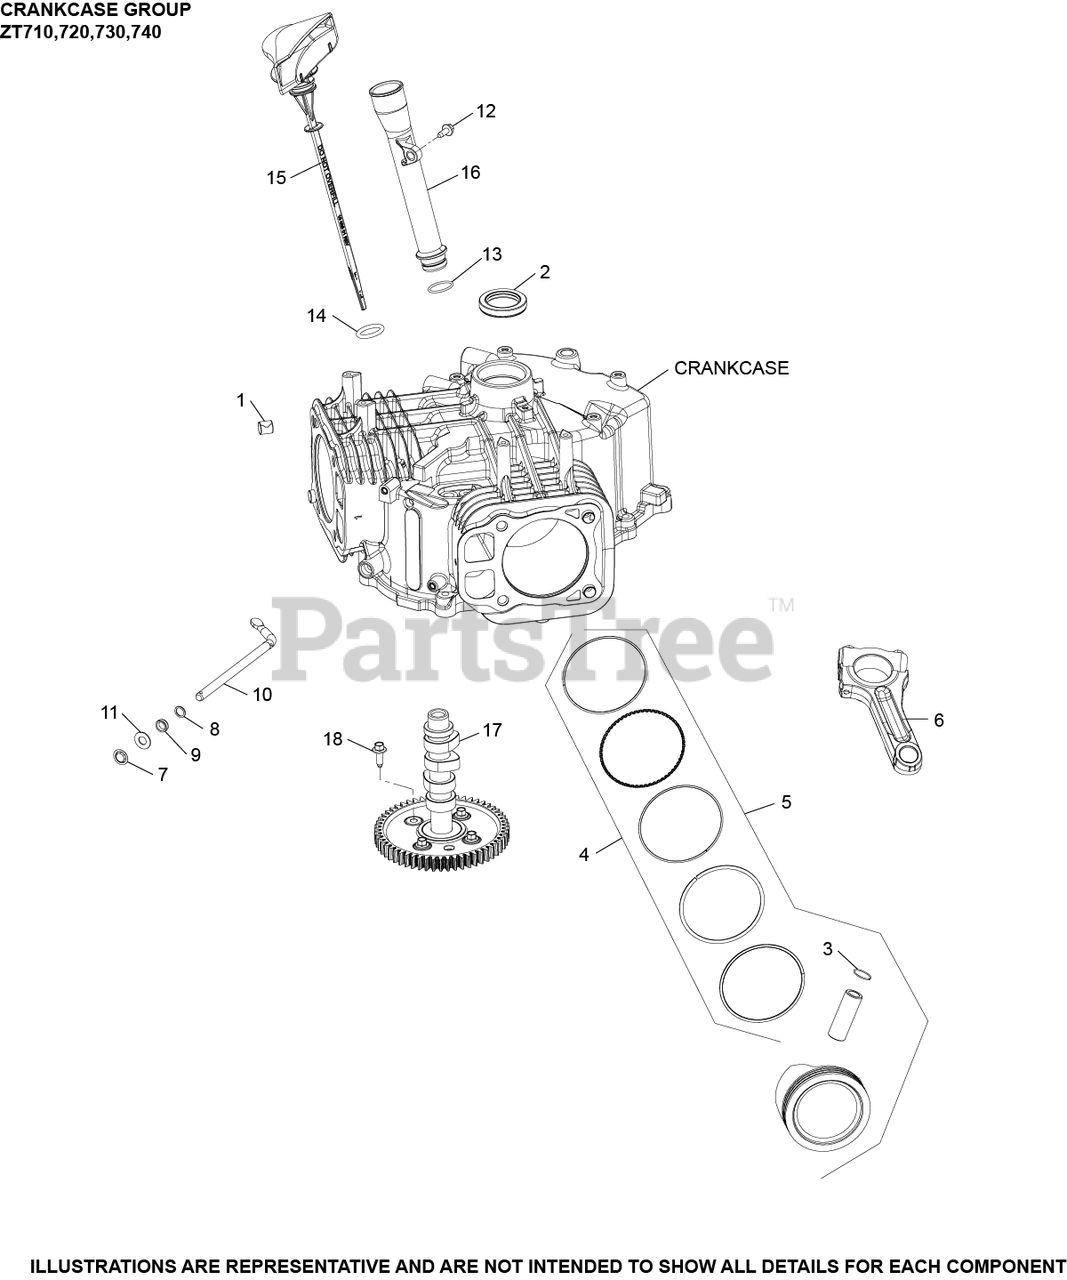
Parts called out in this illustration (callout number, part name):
1	PIN, LOCATING
2	SEAL, OIL (HELIX LIP)
3	RETAINER, PISTON PIN
4	RING SET(STD)STYLE B-1.2mm Tp RING THICK
4	RING SET(.08)STYLE B-1.2mm Tp RING THICK
4	RING SET(.25)STYLE B-1.2mm Tp RING THICK
4	RING SET(.50)STYLE B-1.2mm Tp RING THICK
5	PISTON W/RINGS (STYLE B)(STD) - RING SET 25 108 01-S
5	PISTON W/RINGS (STYLE B)( 0.08) - RING SET 25 108 02-S
5	PISTON W/RINGS (STYLE B)(0.25) - RING SET 25 108 03-S
5	PISTON W/RINGS (STYLE B)(0.50) - RING SET 25 108 04-S
6	ROD, ASSY CONNECTING (STD)-(#2406730S)
6	ROD ASSY, CONNECTING U/S (.010”) (.25 mm) -USE 24 067 31-S
7	RETAINER, RING
8	WASHER, FLAT 11/32"
9	SEAL, GOVERNOR CROSS SHAFT
10	SHAFT, GOVERNOR CROSS
11	WASHER, FLAT 9 MM
12	SCREW, THREAD FORMING
15	DIPSTICK ASSEMBLY
16	TUBE ASSEMBLY, OIL FILL
17	CAMSHAFT ASSEMBLY - WITH ACR
